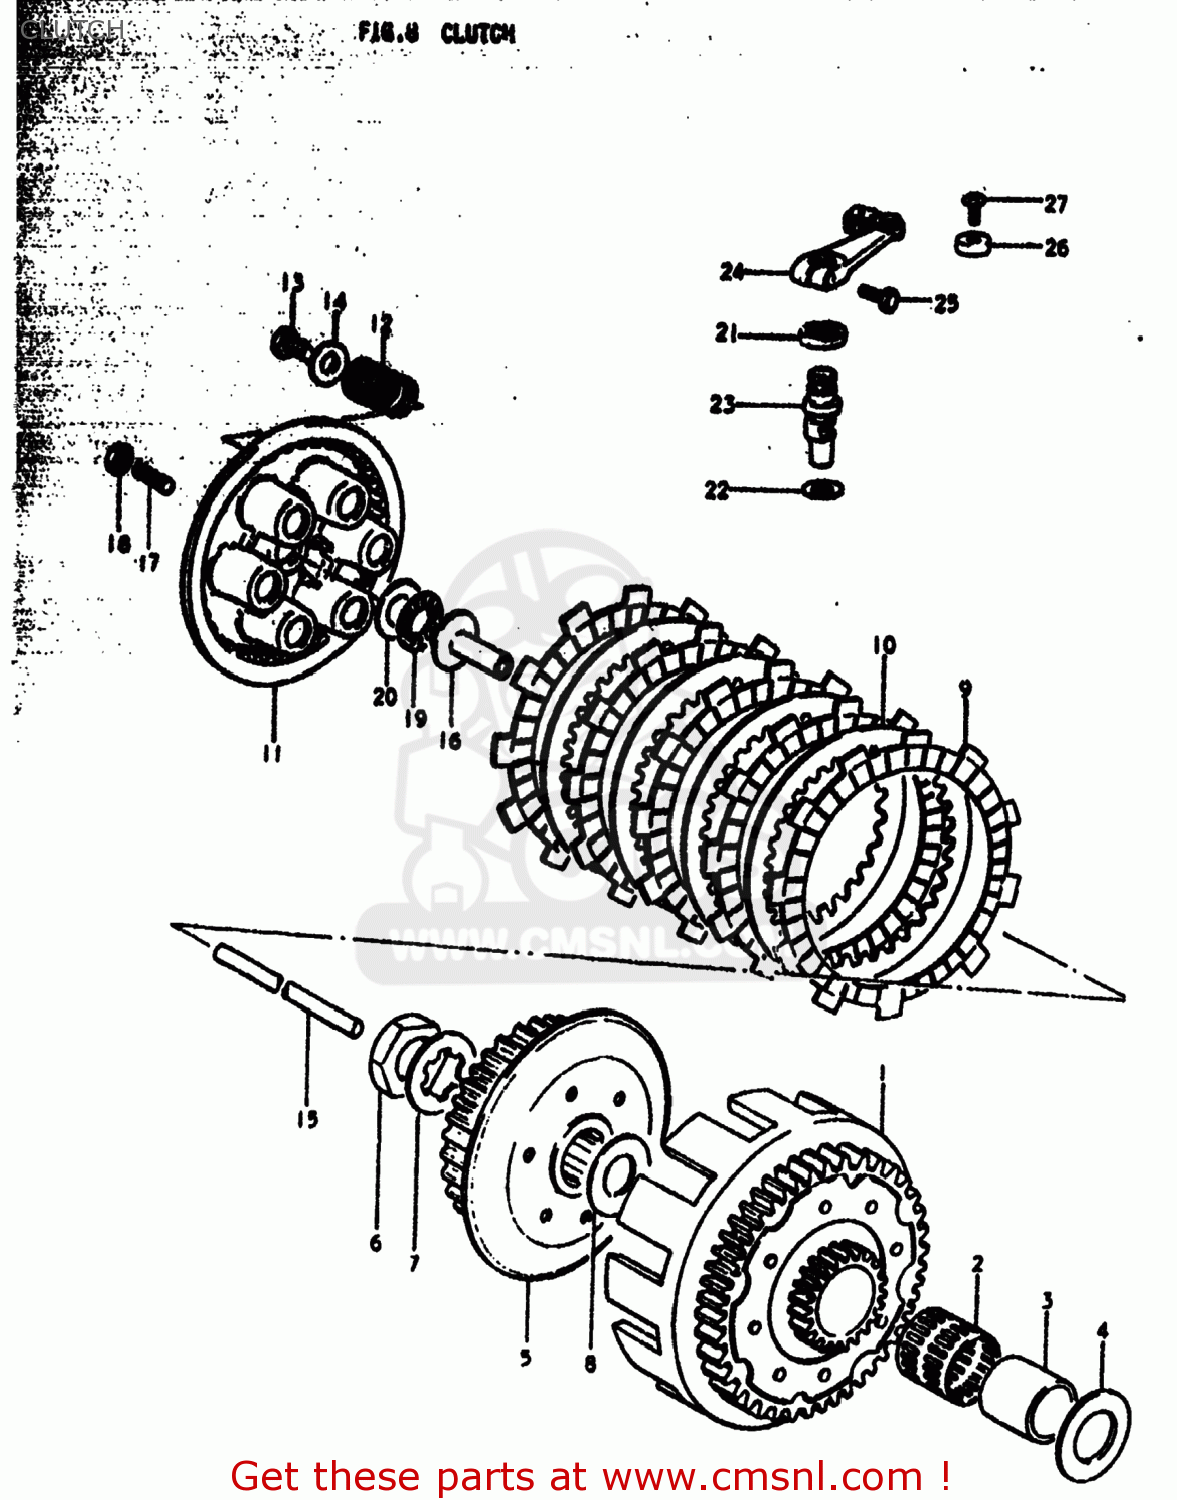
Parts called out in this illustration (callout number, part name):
1	GEAR ASSEMBLY,PRIMARY DRIVE
2	ROLLER BEARING (25X30X2
3	SPACER
4	WASHER(20X38X2)
5	HUB,CLUTCH SLEEVE
6	NUT (20MM)
7	WASHER,LOCK
8	WASHER(20X38X2)
9	PLATE,CLUTCH DRIVE (MCA)
10	PLATE,CLUTCH DRIVEN (NAS)
11	DISC,CLUTCH PRESSURE
12	SPRING
13	BOLT, UPPER
14	WASHER
15	ROD,CLUTCH PUSH
16	PIECE,CLUTCH PUSH
17	SCREW
18	NUT 6MM
19	BEARING(15X28X2)
20	WASHER
21	OIL SEAL
22	WASHER (14.2X22X1)
23	SHAFT,CLUTCH RELEASE C
24	ARM,CLUTCH RELEASE
25	BOLT
26	GUIDE,CLUTCH CABLE
27	SCREW
